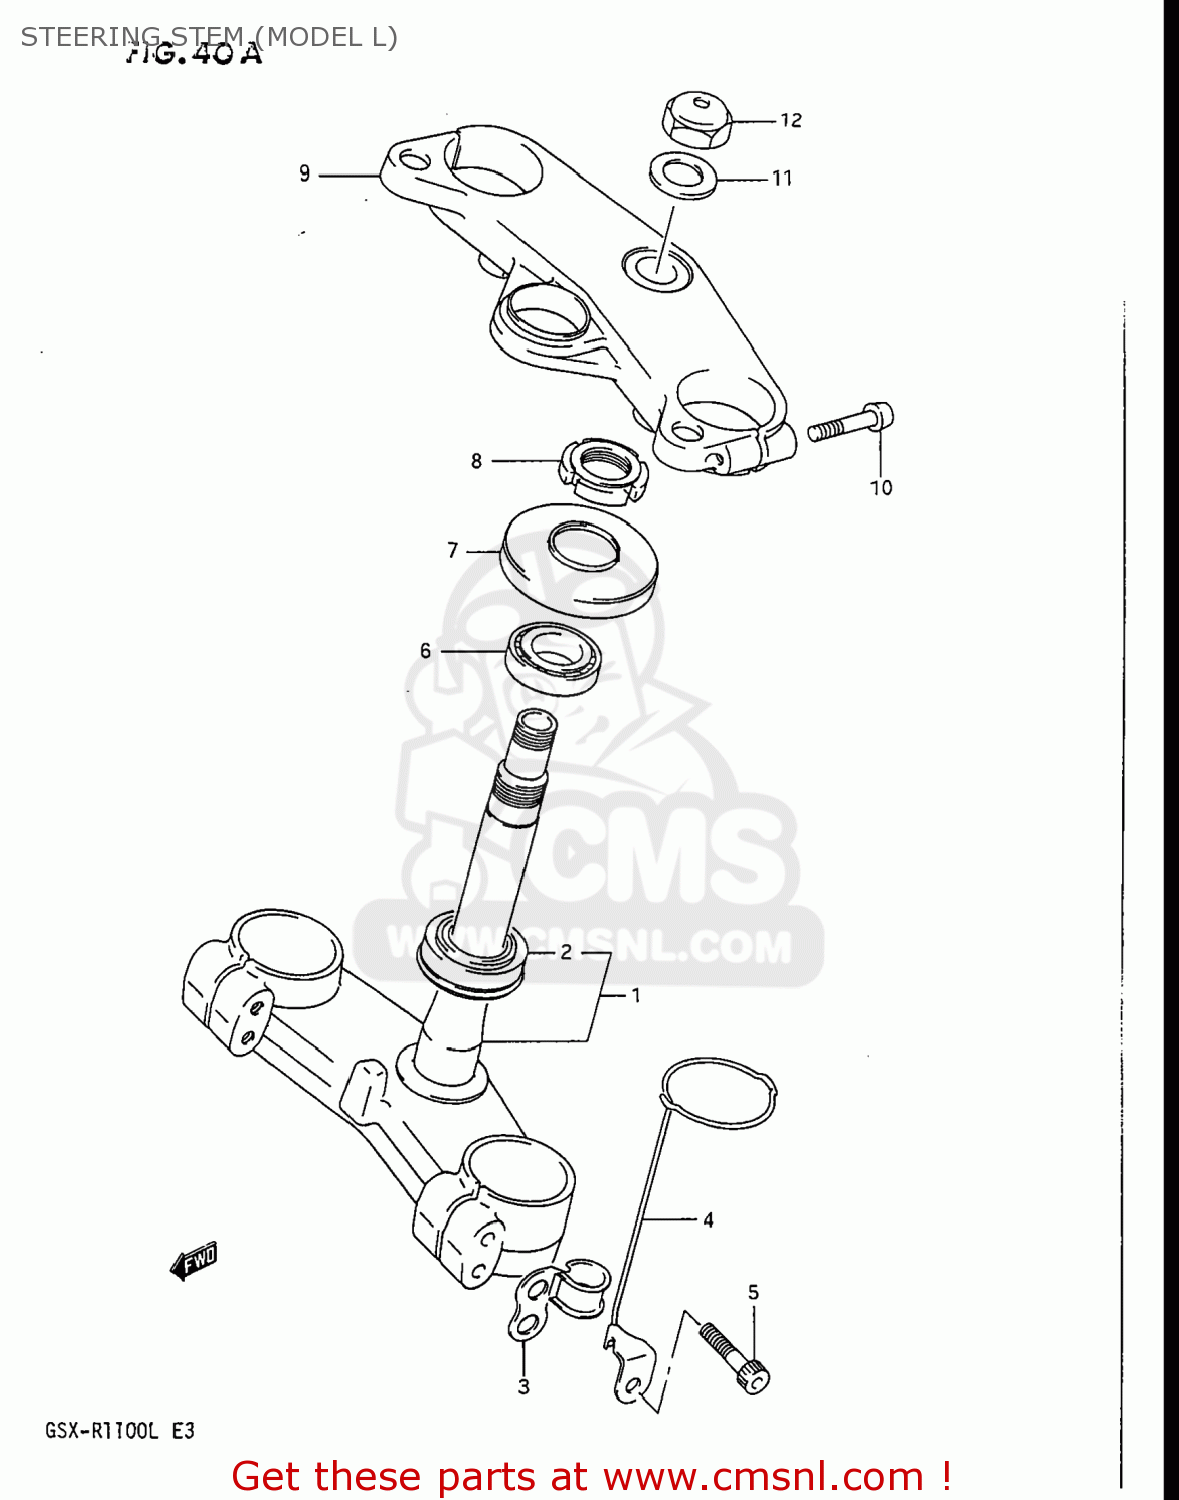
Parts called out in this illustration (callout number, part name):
1	STEM,STEERING
2	BEARING(30X55X17)
3	GUIDE,METER CABLE NO.2
4	HOLDER,STEERING DAMPER
5	BOLT
6	TAPER,ROLLER BEARING
7	SEAL OIL
8	NUT,STEERING STEM(25X44X10)
9	STEM HEAD,STEERING
10	BOLT,FORK INNER TUBE F
11	WASHER(22.5X32X1.6)
12	NUT
